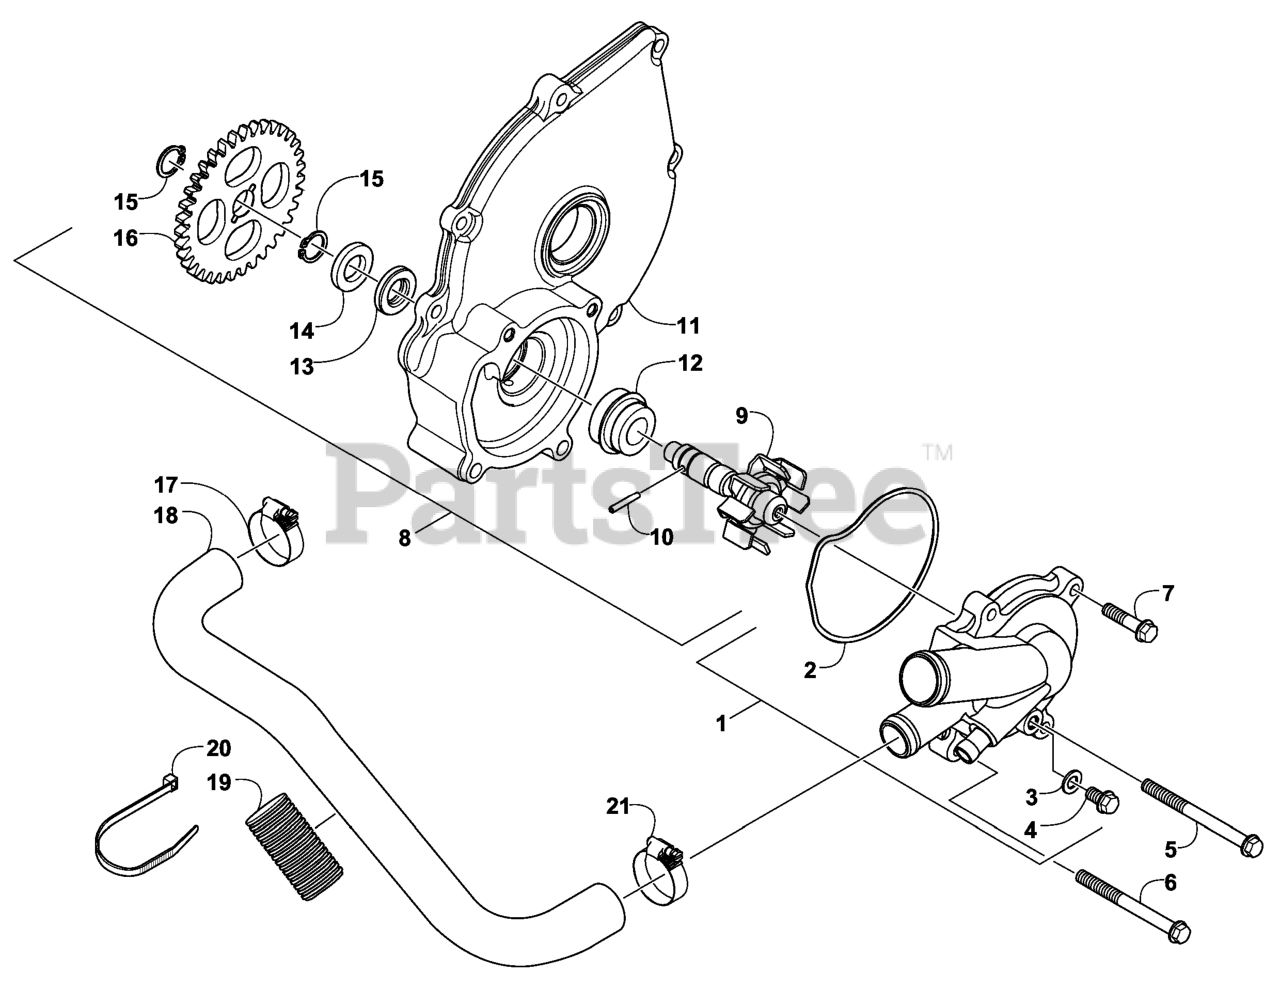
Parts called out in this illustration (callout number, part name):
1	COVER ASM, WATER PUMP
2	RING-WATER PUMP
4	BOLT-FLANGE
5	SCREW-HFH
6	BOLT-FLANGE
7	BOLT-FLANGE
8	COVER-L, WATER PUMP
9	SHAFT-IMPELLER, WATER PUM
12	SEAL-MECHANICAL
13	SEAL-OIL
14	WASHER-THRUST
15	CLIP-CIR
16	GEAR-DRIVEN, WATER PUMP
18	HOSE-WATER
19	CONDUIT-FLEXIBLE, HI TEMP
20	TIE-CABLE
